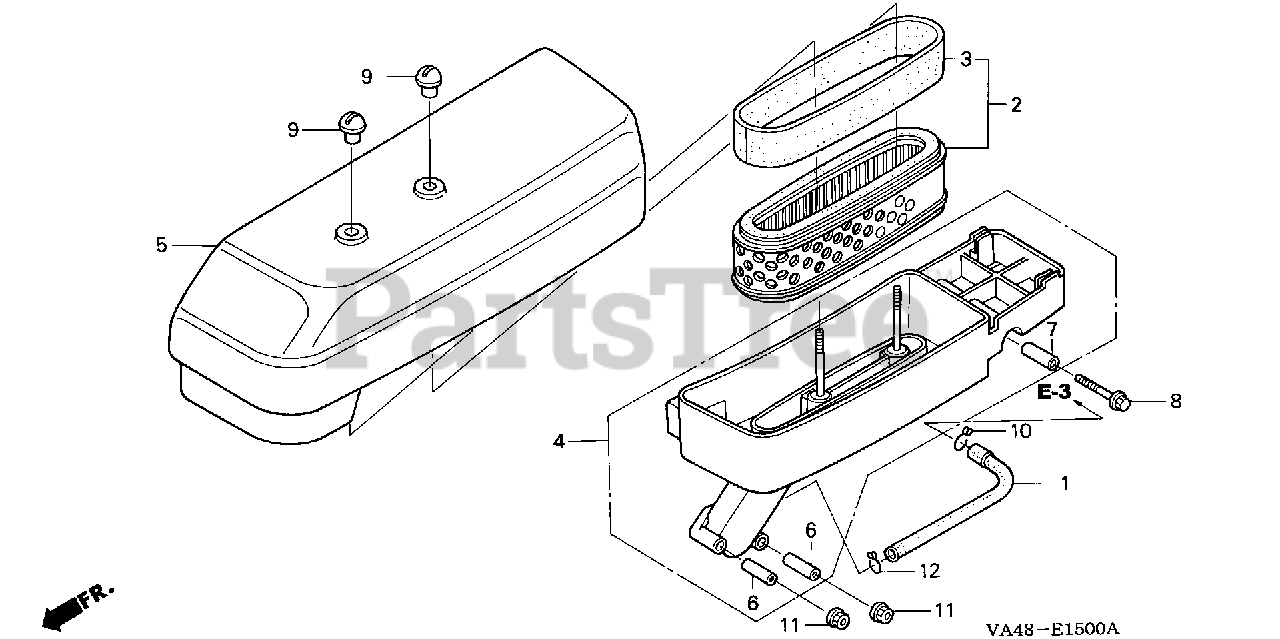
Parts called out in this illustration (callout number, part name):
1	TUBE, BREATHER
2	ELEMENT, AIR CLEANER
3	FILTER (OUTER)
4	HOUSING, AIR CLEANER
5	COVER, AIR CLEANER *R8* (BRIGHT RED)
6	COLLAR, AIR CLEANER Use from Engine SN 1786085.
7	COLLAR B, AIR CLEANER
8	BOLT, FLANGE (6X35)
9	NUT, AIR CLEANER COVER (6MM)
10	CLIP, TUBE
11	NUT, FLANGE (6MM)
12	CLIP, TUBE (B12) Use from Engine SN 2086984.
